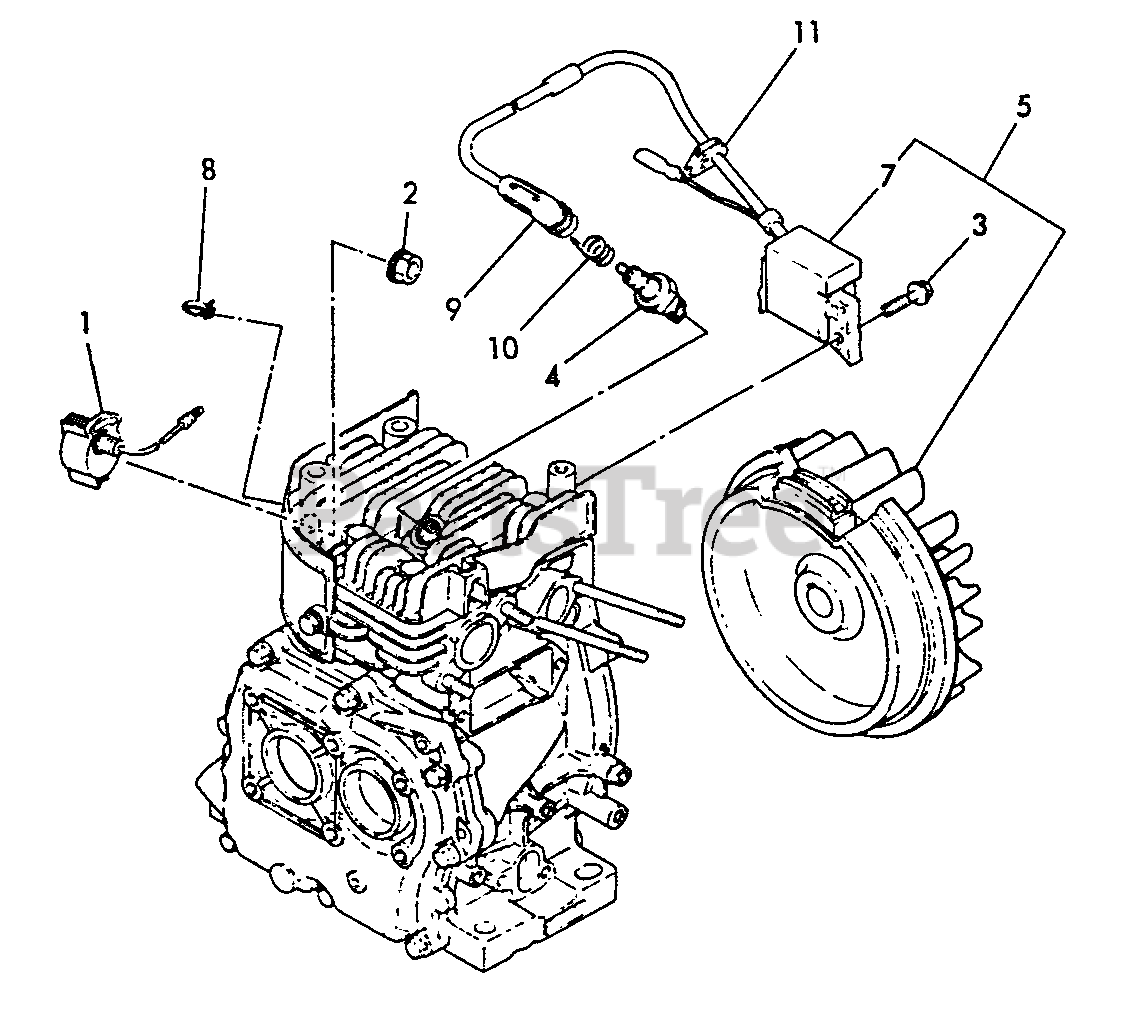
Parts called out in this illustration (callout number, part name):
1	IGNITION SWITCH ASSY
2	NUT - 8
3	BOLT - 6X25
4	SPARK PLUG
5	FLYWHEEL
7	COIL, IGNITION
8	CLAMP
9	CAP, PLUG
10	TERMINAL, SPARK PLUG CAP
11	GROMMET
